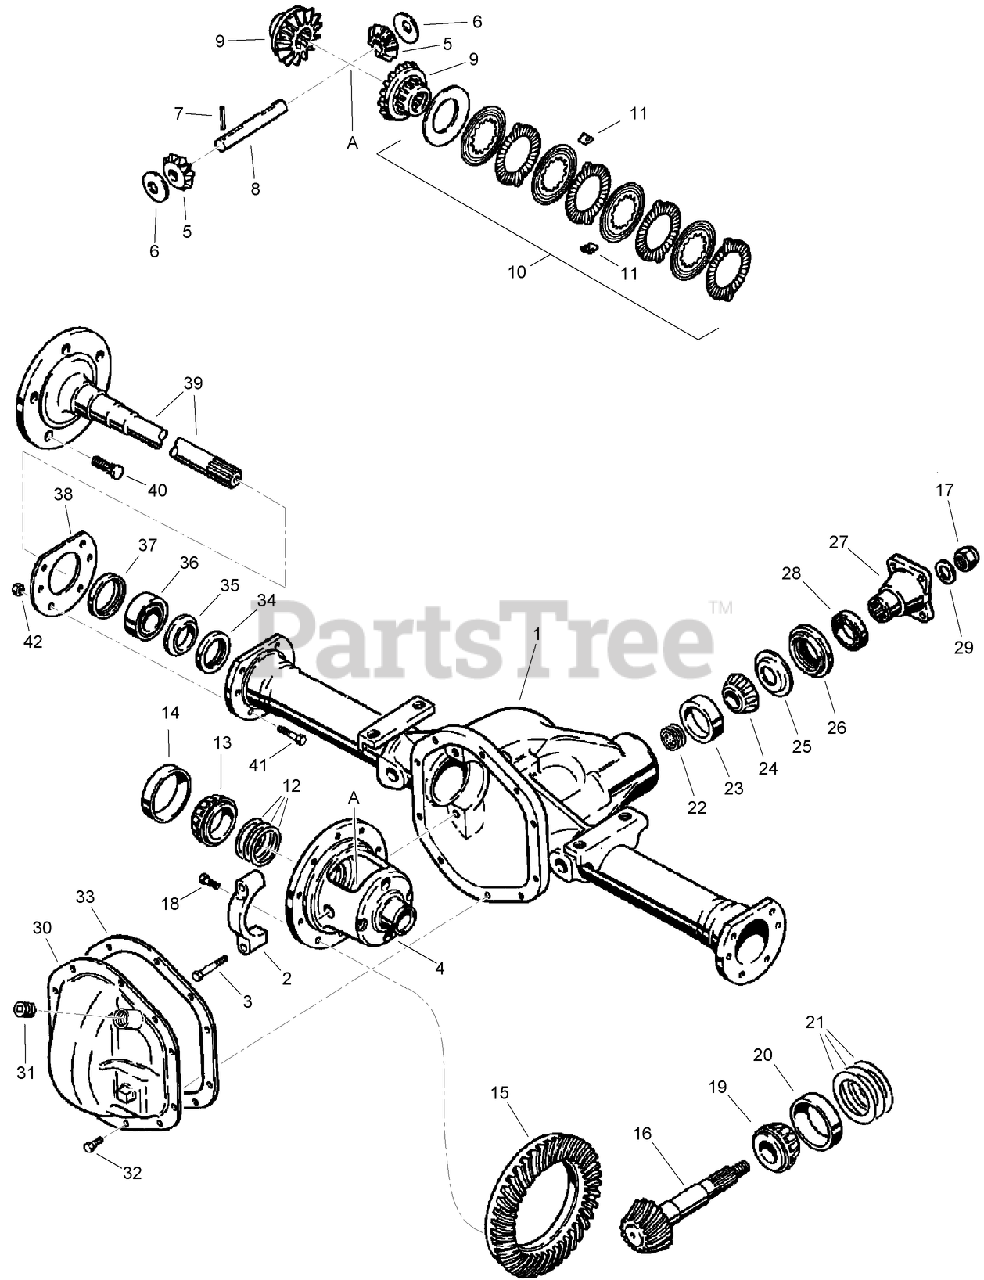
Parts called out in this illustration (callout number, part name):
1	HOUSING - Axle
2	CAP - Differential Bearing
3	BOLT-Hex Hd 0.500 x 2.25 GR8 ZND
5	GEAR - Pinion
6	WASHER - Thrust, Pinion
7	PIN-SPRING, SLOTTED
8	SHAFT - Pinion
9	GEAR - Side, Axle Shaft
10	DIFFERENTIAL DISC KIT (MATCHED SET)
13	BEARING-TAPER
14	CUP - Tapered Roller Bearing
15	GEAR - Ring, Differential Case
16	SHAFT - Pinion, Input
17	NUT - Hex, Special, Yoke Retaining
19	BEARING-TAPER
20	CUP-BEARING
23	CUP - Tapered Roller Bearing, Pinion Shaft, Outer
24	BEARING-TAPER
25	SLINGER - Oil, Pinion Shaft, Inner
27	END-YOKE
28	SLINGER
30	COVER - Differential
31	PLUG - Square Socket 3/4 inch PT, Magnetic
33	GASKET - Cover (service with M20704 gasket, see below)
35	RING - Retaining, Seal
36	BEARING - Ball, Wheel
37	SEAL - Oil, Axle Shaft, Outer
38	RETAINER - Wheel Bearing
39	SHAFT - Axle
40	BOLT - Special, Wheel Retaining
42	NUT-HEX
